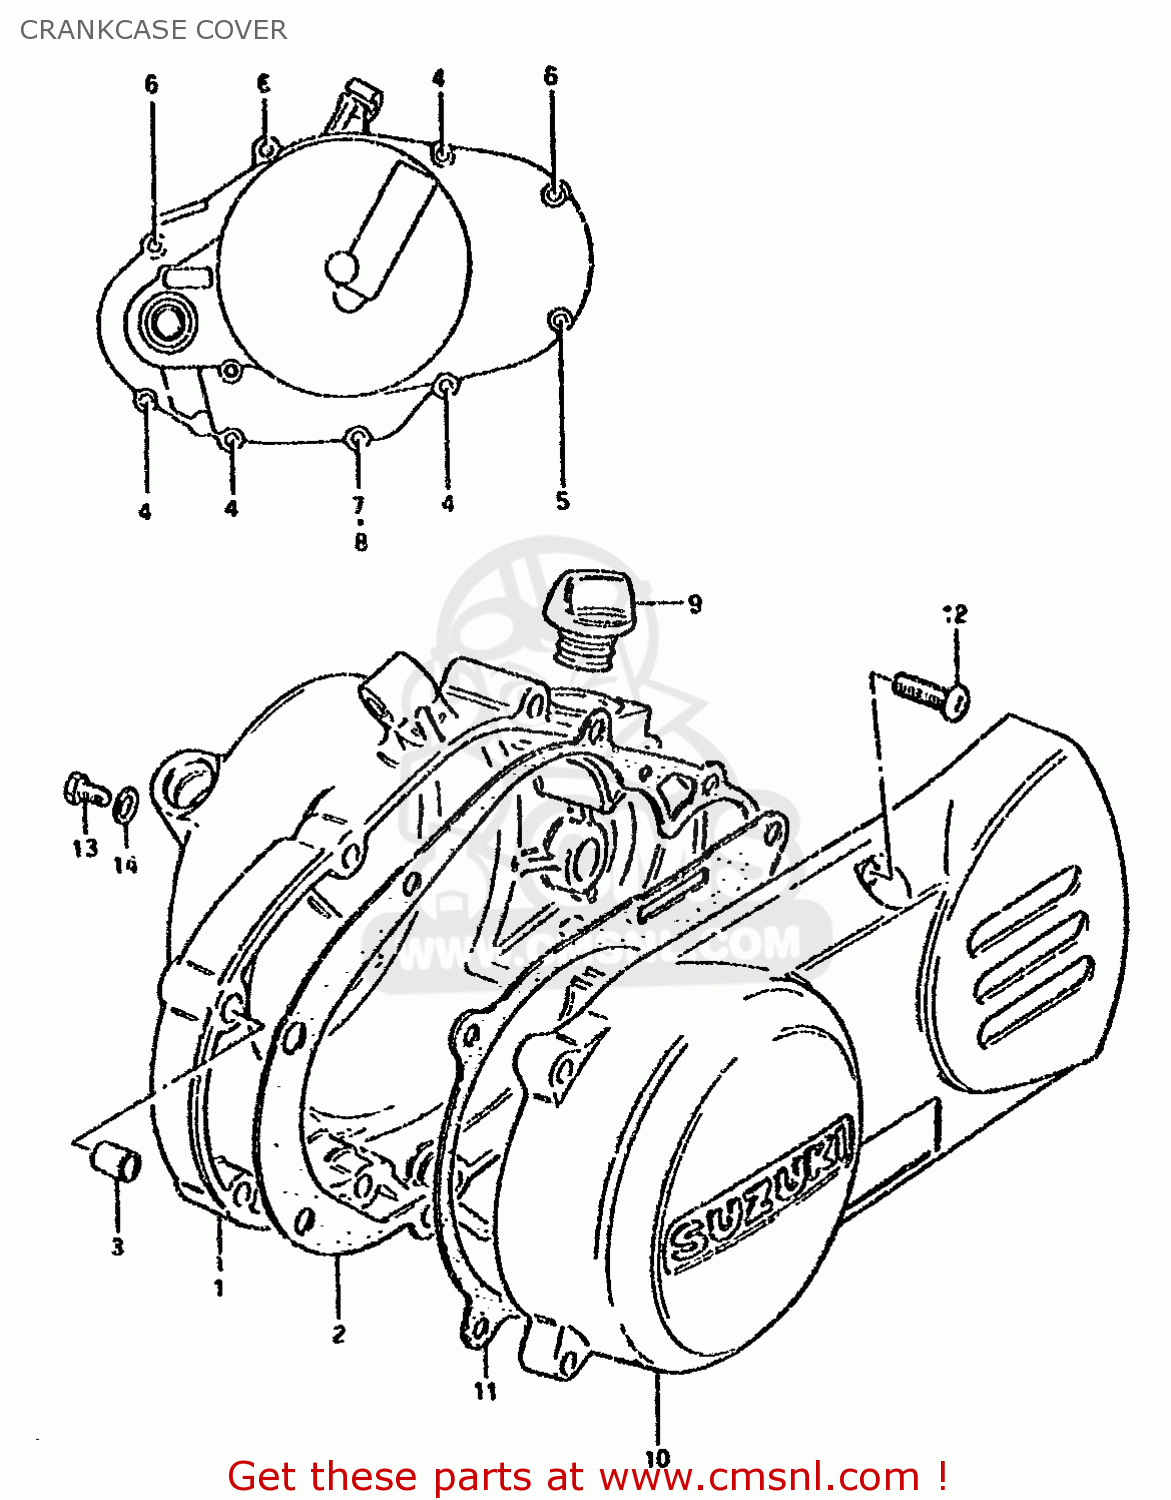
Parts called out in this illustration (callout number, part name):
1	COVER,CLUTCH
2	GASKET,CLUTCH COVER (NAS)
3	PIN
4	SCREW
5	SCREW
6	SCREW
7	SCREW
8	GASKET(6.2X11X1).2 (NAS)
9	PLUG
10	COVER,MAGNETO
11	GASKET,MAGNETO COVER (NAS)
12	SCREW
13	SCREW(6X10)
14	GASKET(6.2X11X1) (NAS)
